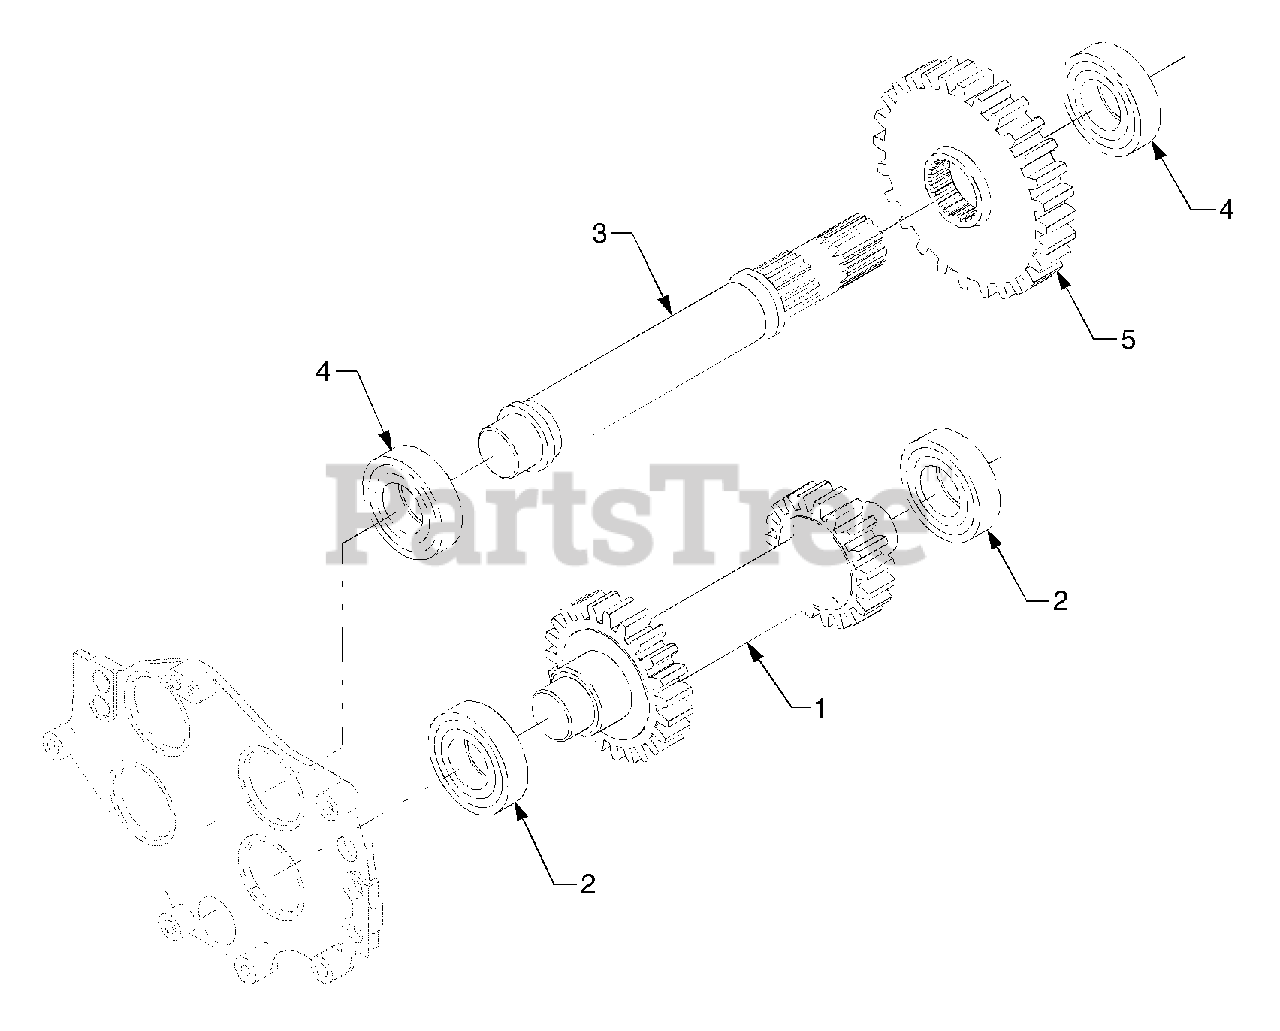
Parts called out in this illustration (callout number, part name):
1	Shaft, 23-19 Gear
2	Bearing, Ball
3	Shaft, Counter (PTO)
4	Bearing, Ball
5	Gear, 33 (PTO)
